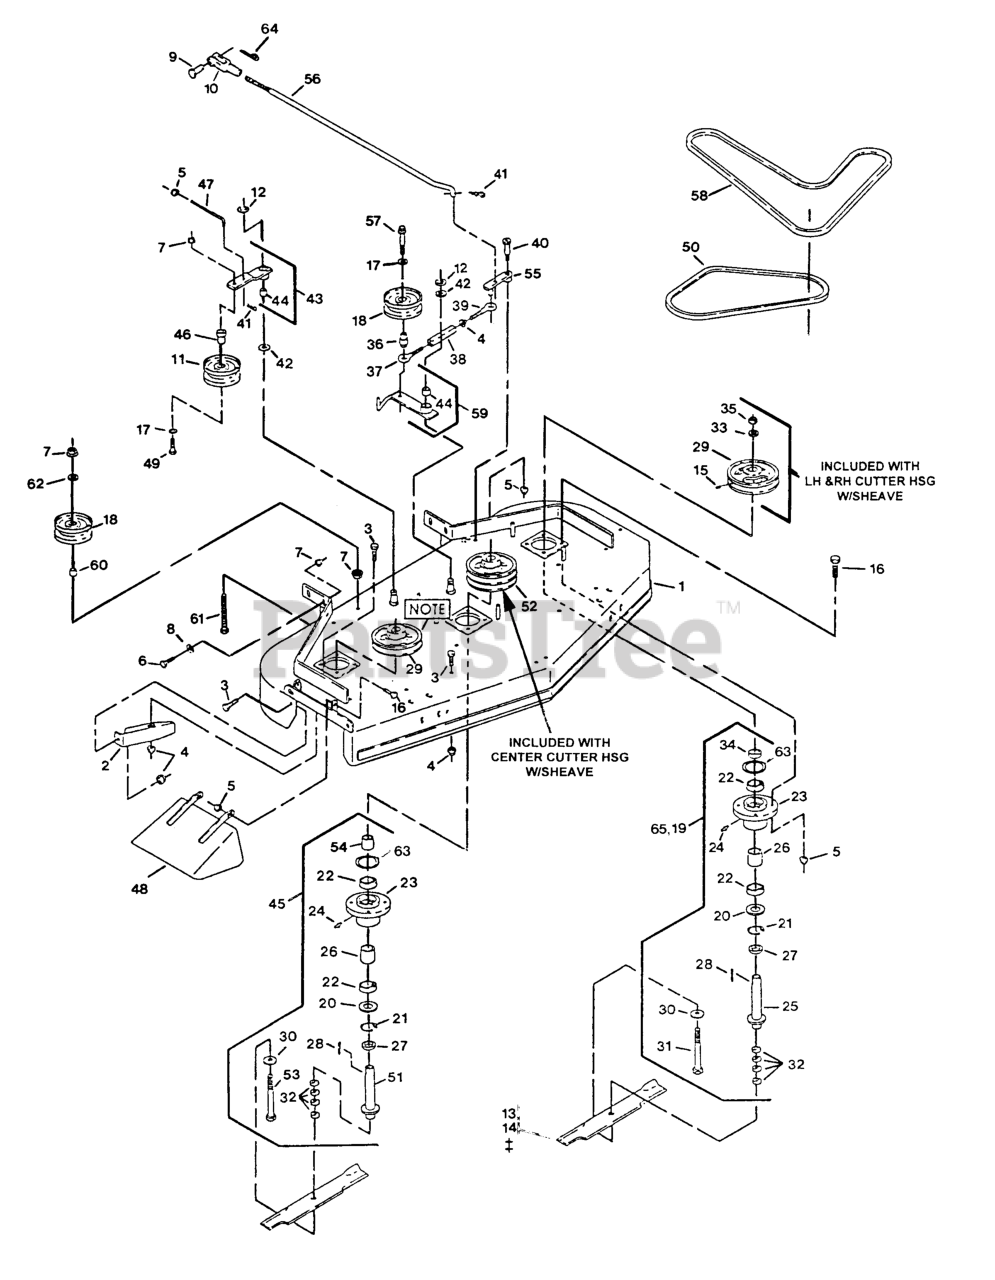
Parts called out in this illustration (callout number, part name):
2	BAFFLE-DOGLEG
9	PIN-CLEVIS
10	YOKE-ADJUSTABLE
11	IDLER,PULLEY
15	SCREW-SET
19	ASM,HOUSING CUTTER
20	SEAL,DUST
21	RING,SNAP WLDS N5000-244
23	HOUSING,CUTTER
26	SPACER,BRG/BRG
27	SPACER,BEARING &SPINDLE
30	WASHER-SPRING
31	SCREW-CAP, HH
33	WASHER-RETAINER, SHEAVE
36	BUSHING-ENGAGEMENT
37	EYEBOLT-THREAD, LH
38	BODY-TURNBUCKLE
39	EYEBOLT-THREAD, RH
40	BOLT,SHLDR KSKH
41	PIN-COTTER
42	WASHER-SPINDLE
43	ARM WLDMNT W/BUSHING
44	BEARING,POWDERED METAL
46	BUSHING-IDLER
47	LINKAGE
50	BELT,FRONT DECK
53	SCRW,CAP HH 5/8-18X8.5
54	SPACER,BEARING/SHEAVE
56	ARM-LINKAGE, ASSIST
58	BELT,BLADE DRIVE 36
60	BUSHING,IDLER
61	BOLT,TAP HH3/8-16X2-1/4
